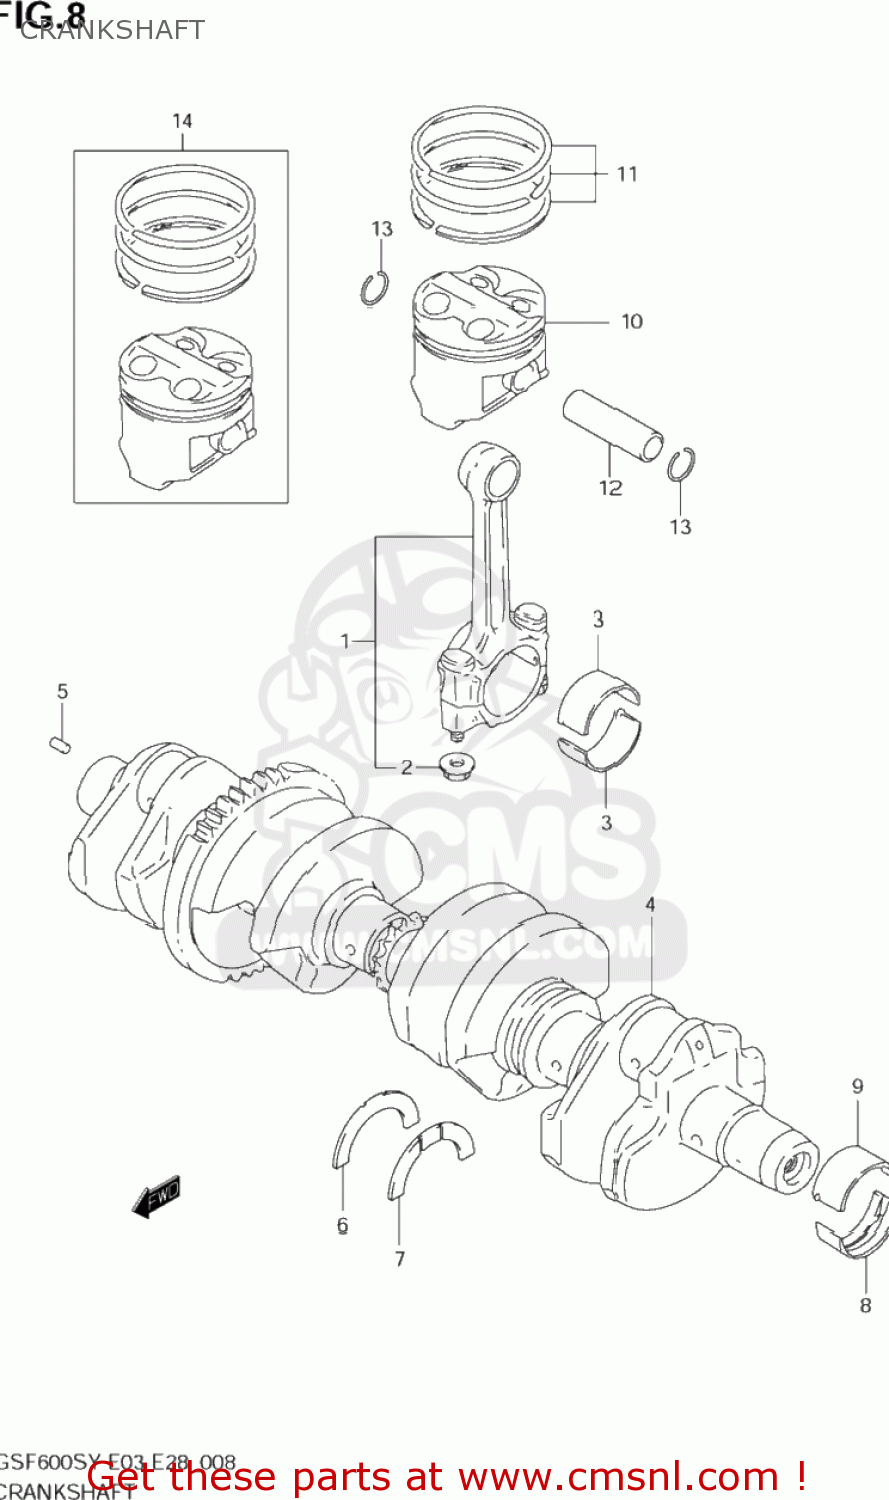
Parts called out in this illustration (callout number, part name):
1	CONNECTING ROD ASSY
2	NUT
3	BEARING,CRANK PIN
4	CRANKSHAFT SET
5	PIN
6	PLATE,CRANK THRUST
7	PLATE,CRANK THRUST
8	BEARING,CRANKSHAFT LWR
9	BEARING,CRANKSHAFT UPR
10	PISTON
11	RING SET,PISTON
12	PIN,PISTON
13	CIRCLIP
14	PISTON SET(OS:0.5)
